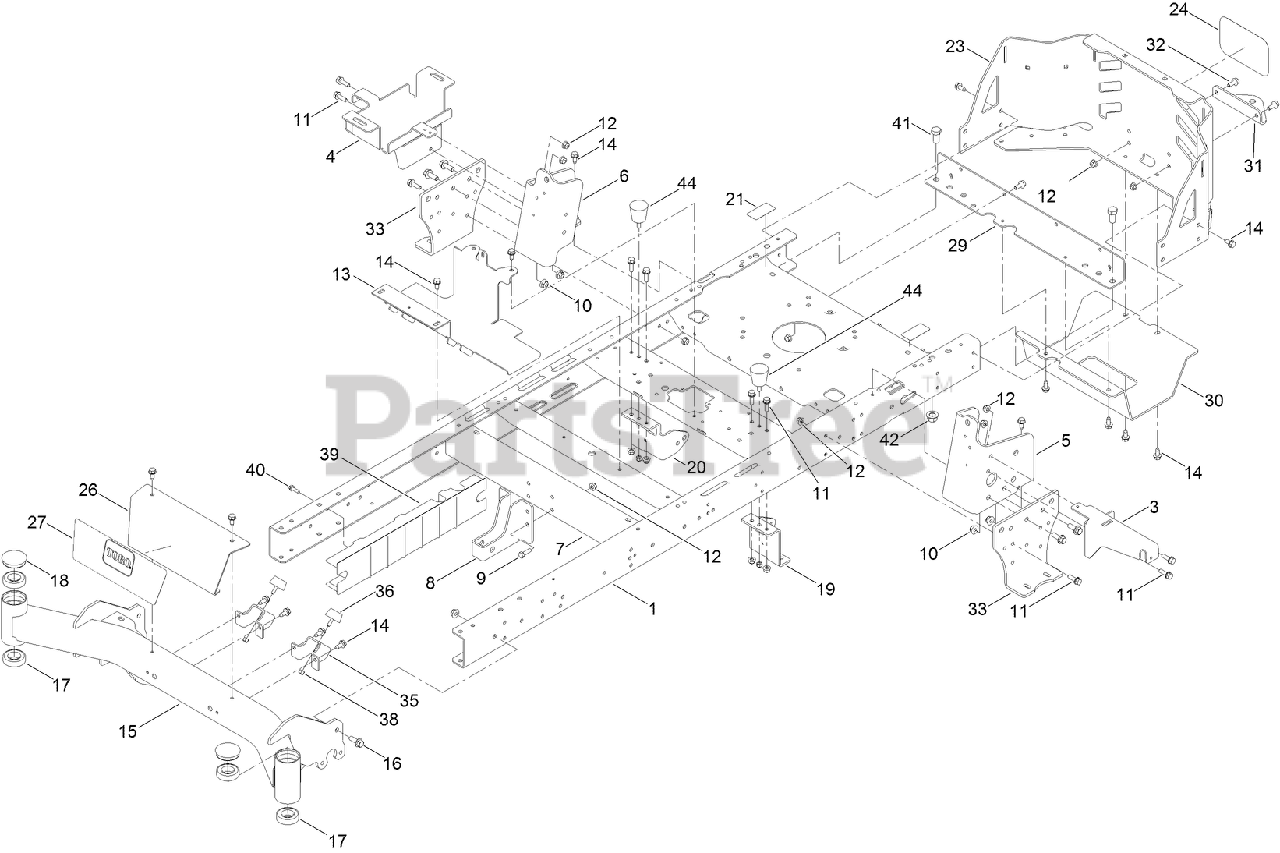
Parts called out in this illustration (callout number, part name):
1	FRAME ASM
3	BRACKET-SUPPORT, POD (LH)
4	TRAY-BATTERY
5	BRACKET-MOUNTING, LH
6	BRACKET-MOUNTING, RH
7	BRACE-CROSS, LOWER
9	SCREW-HH
10	NUT-HF, NI
11	SCREW-HHF
12	NUT-HF, NI
13	BRACKET-MOUNT
14	SCREW-HWHTF
15	AXLE-FRONT
16	SCREW-HHF
17	BEARING-BALL
18	CAP-GREASE
19	MOUNT-HYDRO, FRONT (LEFT)
20	MOUNT-HYDRO, FRONT (RIGHT)
21	DECAL-BYPASS
23	GUARD-ENGINE
24	DECAL
26	PLATE-FRONT
27	DECAL-TIMECUTTER HD
30	GUARD-MUFFLER
31	BRACKET-HITCH
32	SCREW-HHF
33	MOUNT-HYDRO
35	BRACKET-STOP, BUMP
36	BUMPER
38	NUT-LOCK, NI
39	GUARD-RAIL
40	SCREW-HWH
41	SCREW-HH
42	NUT-LOCK
44	BUMPER-RUBBER
